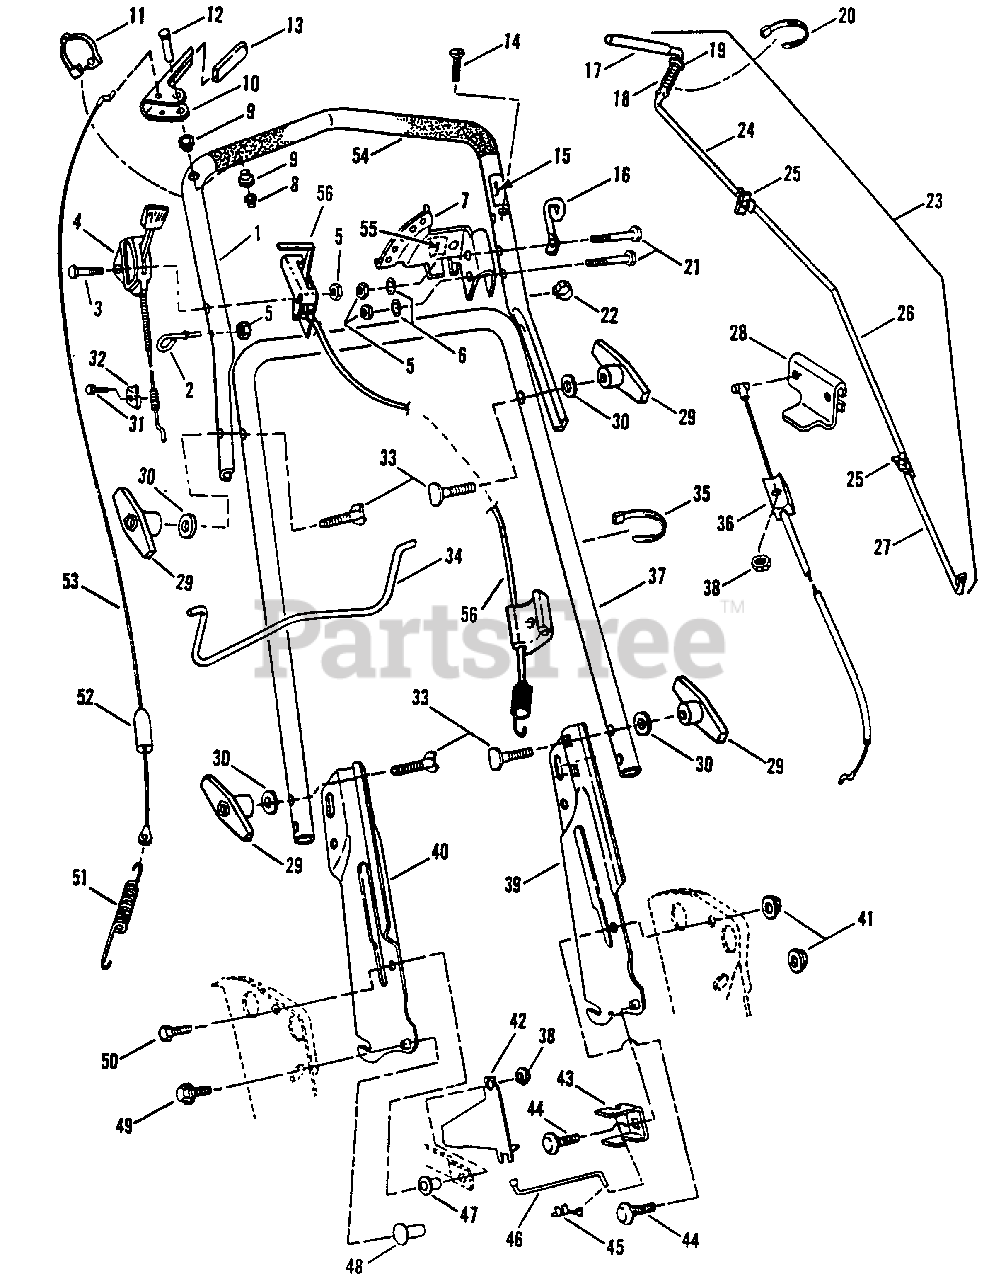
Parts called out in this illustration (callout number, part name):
1	HANDLE, Upper
2	GUIDE, Pull Rope (Right Side)
3	SCREW, 1/4-20 x 1-3/4 Hex Head Cap, Grade 5
4	CONTROL, Throttle 48.0"
5	NUT, 1/4-20 Hex
6	WASHER, 1/4 Internal Tooth Lock
7	SECTOR, Speed
8	PUSH-NUT
9	BUSHING
10	HANDLE, Wheel Drive
11	CLAMP, 7/8" Double Cable
12	PIN, Clutch Cable
13	GRIP, Wheel Drive Handle
14	SCREW, 5/16-24 x 1-1/2" Machine, Grade 5
15	DECAL, Blade Control (Left Side)
16	GUIDE, Pull Rope (Left Side)
17	GRIP, Speed Control Handle
18	SPRING, Speed Control
19	WASHER, 3/8" Flat
20	TIE, Wire
21	SCREW, 1/4-20 x 1-1/2" Hex Head Cap, Grade 5
22	CLIP, Cable Wiring
23	ASSEMBLY, Speed Control Lever
24	ROD, Upper
25	WING-NUT, 1/4-20
26	ROD, Intermediate
27	ROD, Lower
28	CLIP, Blade Control
29	T-KNOB, 5/16-18 Thread
30	WASHER, 5/16 Internal Tooth Lock
31	SCREW, #10-32 x 5/8" Hex Head Cap
32	CLAMP, Casing
33	SCREW, 5/16-18 x 1-7/8" Curved Head, Grade 2
34	BAIL, OPC Control (16.6" Wide)
35	TIE, Wire
36	CABLE, Blade Control
37	HANDLE, Middle
38	NUT, 5/16-24 Hex Center Lock, Grade 5
39	BRACKET, Middle Handle (Left Side)
40	BRACKET, Middle Handle (Right Side)
41	NUT, 5/16-18 Hex Flange Lock, Grade 5
42	GUIDE, Lower V-Belt
43	ANCHOR, Speed Control
44	BOLT, 5/16-18 x 5/8" Carriage, Grade 5
45	CLIP, Transfer Rod
46	ROD, Transfer
47	BUSHING, Differential
48	TEE-NUT, 5/16-18 Thread
49	BOLT, 5/16-18 x 3/4" Hex Flange Lock, Grade 5
50	SCREW, 5/16-24 x 1" Hex Head Cap, Grade 5
51	SPRING, Clutch
52	COVER, Vinyl
53	CABLE, Clutch Pull (Z-Bend)
54	GRIP, Foam
55	DECAL, Speed Select
56	CABLE, Swivel Lock
